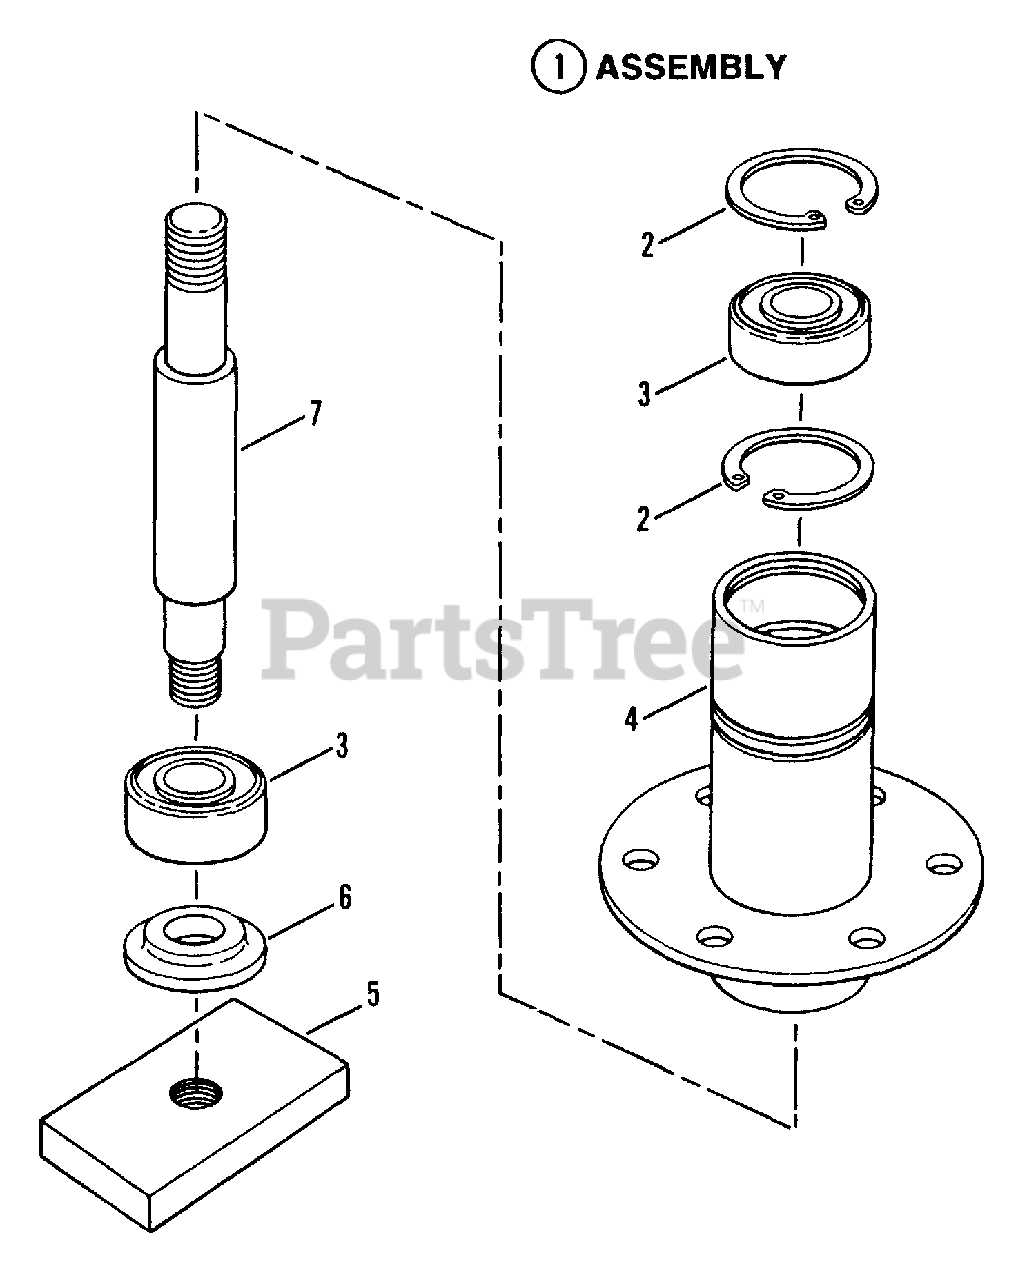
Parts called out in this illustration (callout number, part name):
1	ASSEMBLY, Spindle Housing, 42" Cutting Deck (Left Hand)
1	ASSEMBLY, Spindle Housing, 42" Cutting Deck (Right Hand)
2	RING, Retaining
3	BEARING, Spindle
4	HOUSING, Spindle (Left Hand) (4.35")
4	HOUSING, Spindle (Right Hand) (6.1")
5	HOLDER, Blade
6	WASHER, Spindle
7	SPINDLE (Left Hand) (5.75")
7	SPINDLE (Right Hand) (6.5")
